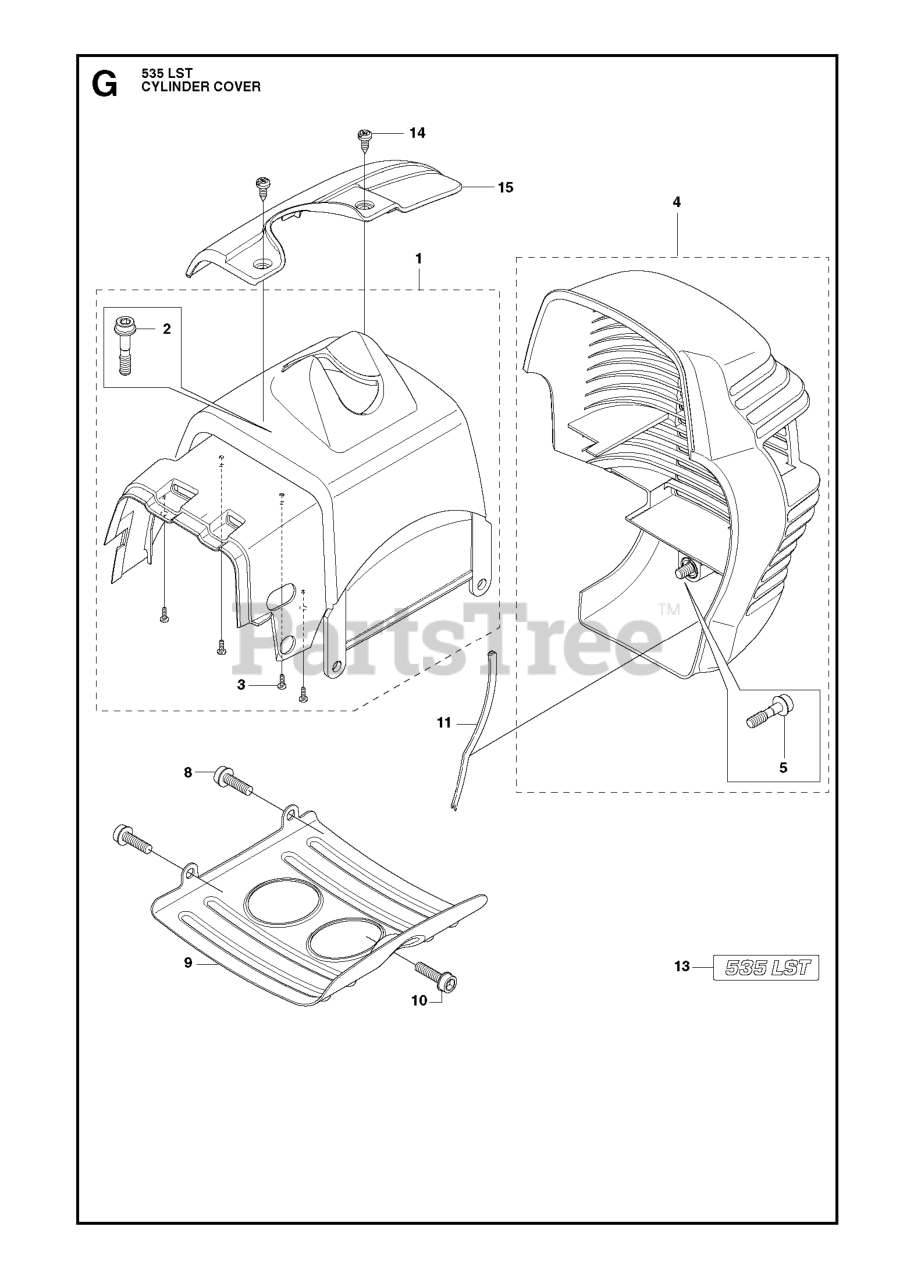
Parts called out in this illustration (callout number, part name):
1	CYLINDER COVER
2	SCREW IHSCFMO
4	HEAT PROTECTOR
5	SCREW IHSCFMO
8	SCREW IHSCFT
10	SCREW IHSCFT
13	LABEL CYLINDER COVER 535LST
14	SCREW CCRPANT ST4.2X9.5 DS
15	ARM PROTECTION
